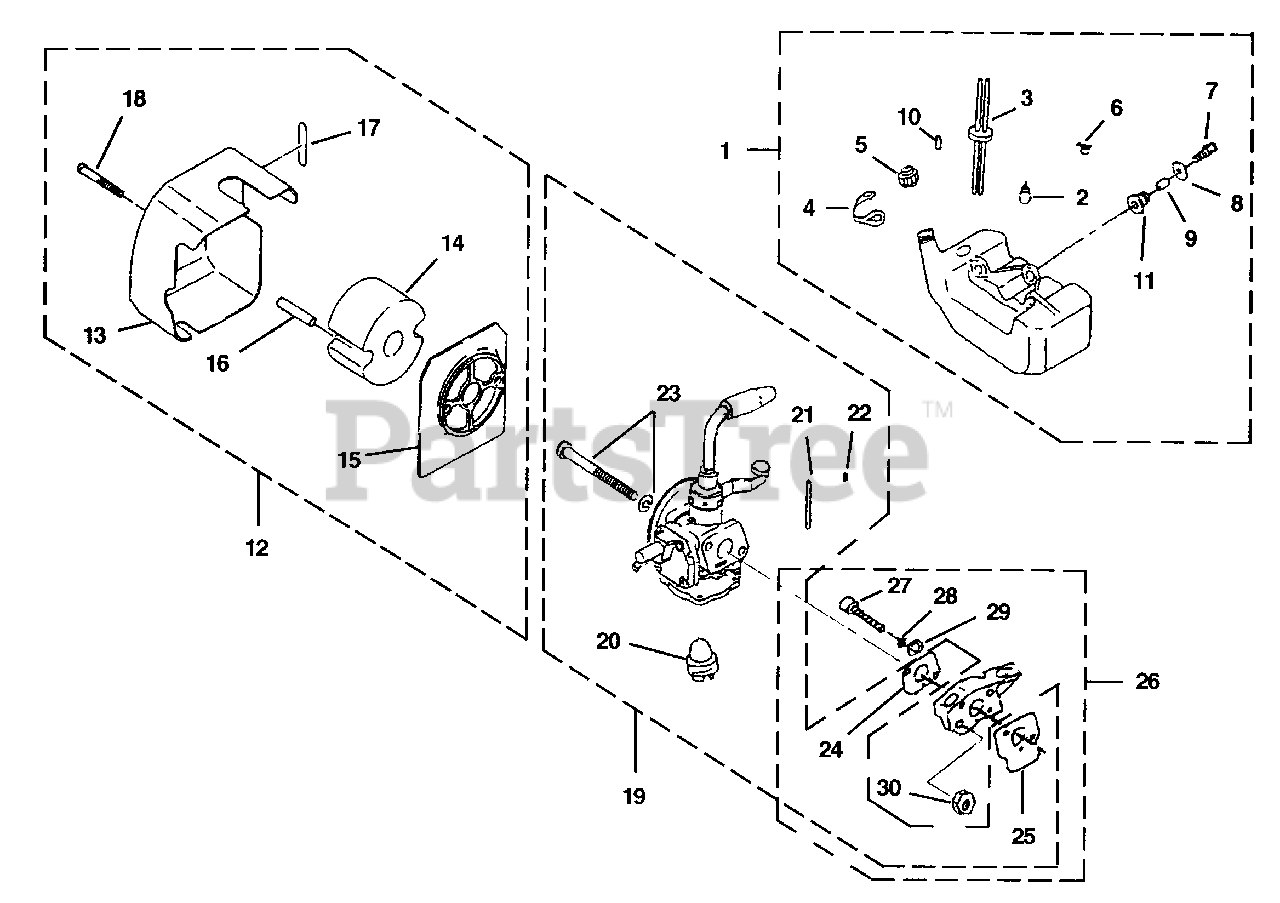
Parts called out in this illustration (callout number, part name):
1	FUEL TANK ASSEMBLY
2	FILTER-Fuel
3	TUBE ASSEMBLY
4	CAP-Retainer
5	CAP - Fuel
6	HOSE CLAMP
11	BUMPER, Fuel Tank
12	AIR FILTER ASSEMBLY
13	BODY - Air Filter
14	FILTER - Air
15	HOLDER - Lead
17	LABEL - Choke
18	SCREW - Pan Hd
19	CARBURETOR ASSY
20	AIR PURGE BULB
24	GASKET - Carburetor
25	GASKET - Heat Dam
26	HEAT DAM ASSEMBLY
27	SCREW - Socket Hd
28	WASHER-Spring
